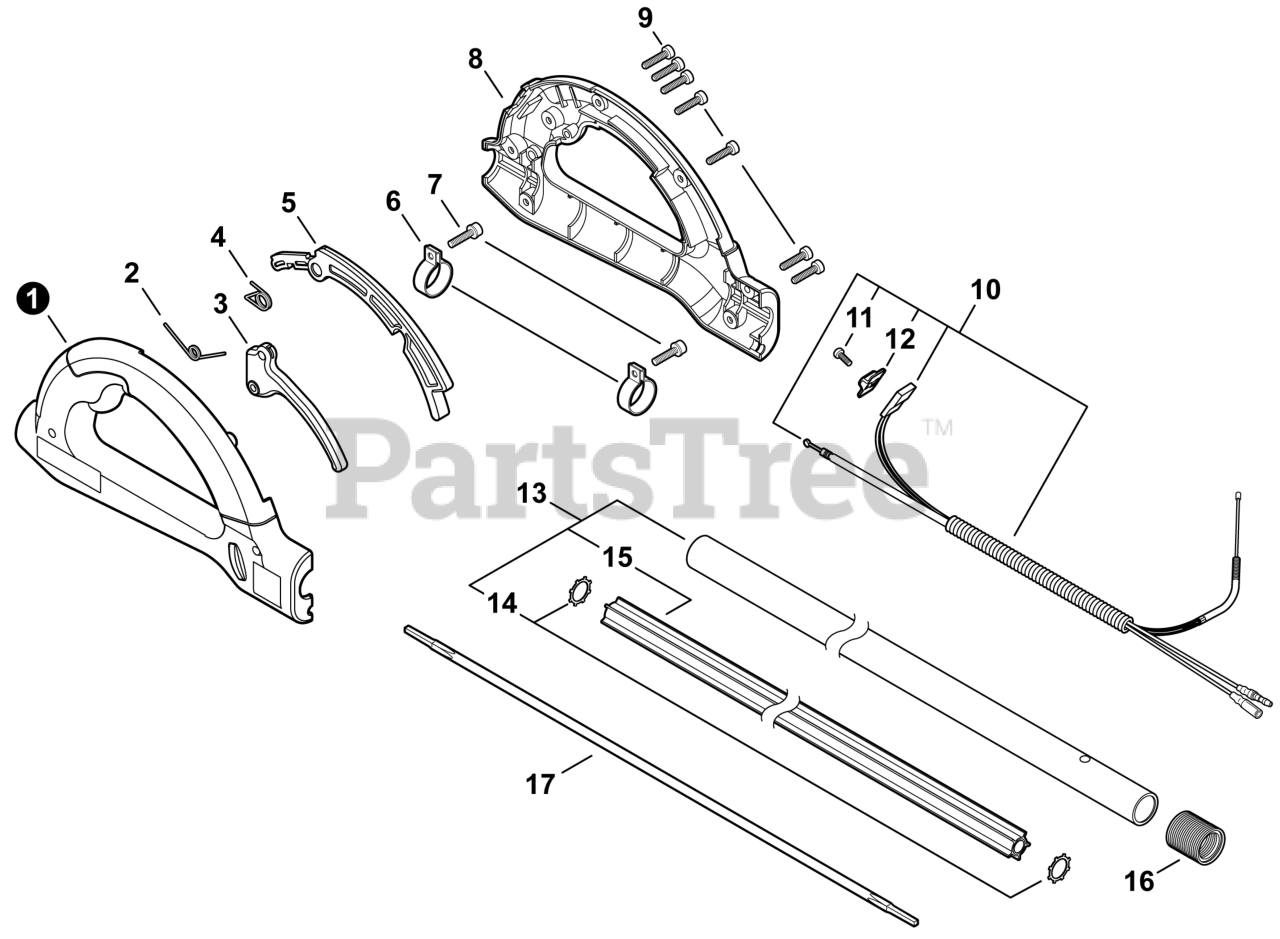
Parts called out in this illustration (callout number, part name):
1	BODY, HANDLE - LEFT
2	SPRING, TORSION
3	TRIGGER, THROTTLE
4	SPRING, TORSION
5	LOCKOUT, THROTTLE
7	BOLT, TORX 5x16
8	BODY, HANDLE - RIGHT
9	BOLT, TORX 5x16
10	CABLE ASSY, CONTROL
11	SCREW 3x10
12	KNOB, SWITCH - ORANGE
13	PIPE, MAIN
16	TUBE, FLEXIBLE
17	DRIVESHAFT - FLEXIBLE
